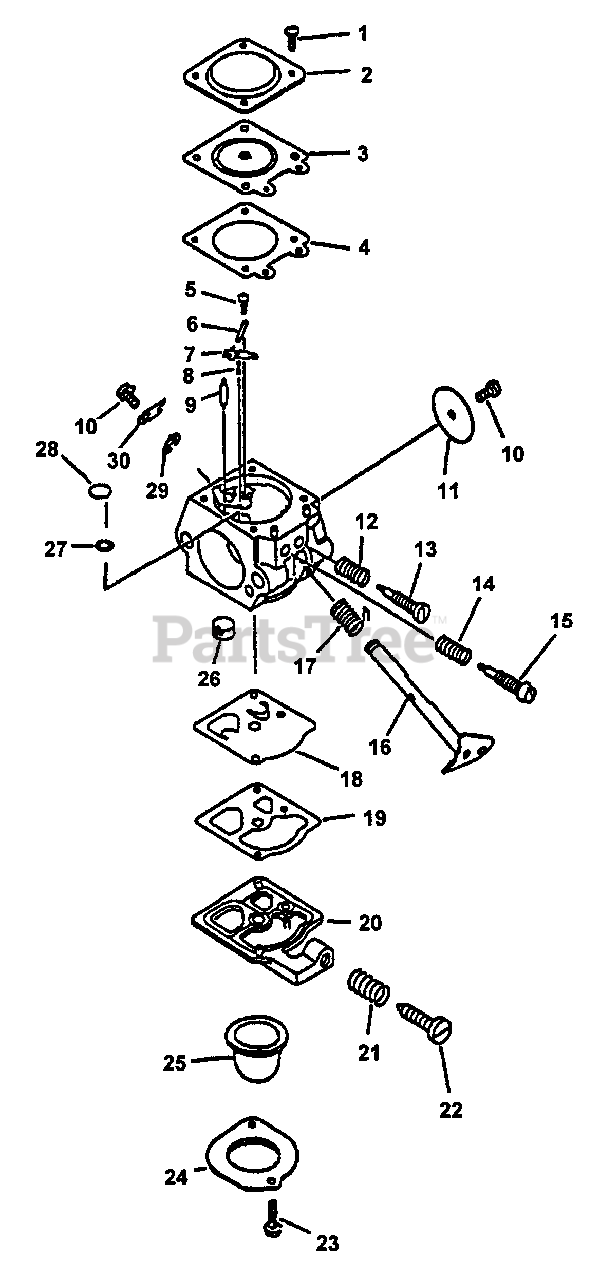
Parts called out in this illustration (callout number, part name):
2	COVER, METERING
3	DIAPHRAGM, METERING
4	GASKET, METERING
5	SCREW, METERING LEVER PIN
6	PIN, METERING LEVER
7	LEVER, METERING
8	SPRING, METERING LEVER
9	VALVE, INLET NEEDLE
11	VALVE, THROTTLE
12	SPRING, LOW NEEDLE
13	NEEDLE - LOW SPEED
14	SPRING, HIGH SPEED NEEDLE
15	NEEDLE - HIGH SPEED
16	SHAFT, THROTTLE
17	SPRING, THROTTLE RETURN
18	DIAPHRAGM, PURGE
19	GASKET, PURGE
20	COVER, PUMP
21	SPRING, IDLE ADJUST
22	SCREW, IDLE ADJUST
24	RETAINER, PURGE BULB
25	BULB, PURGE
26	STRAINER
27	RING, RETAINING
28	PLUG, WELCH
29	RING, RETAINING
30	LEVER, THROTTLE
